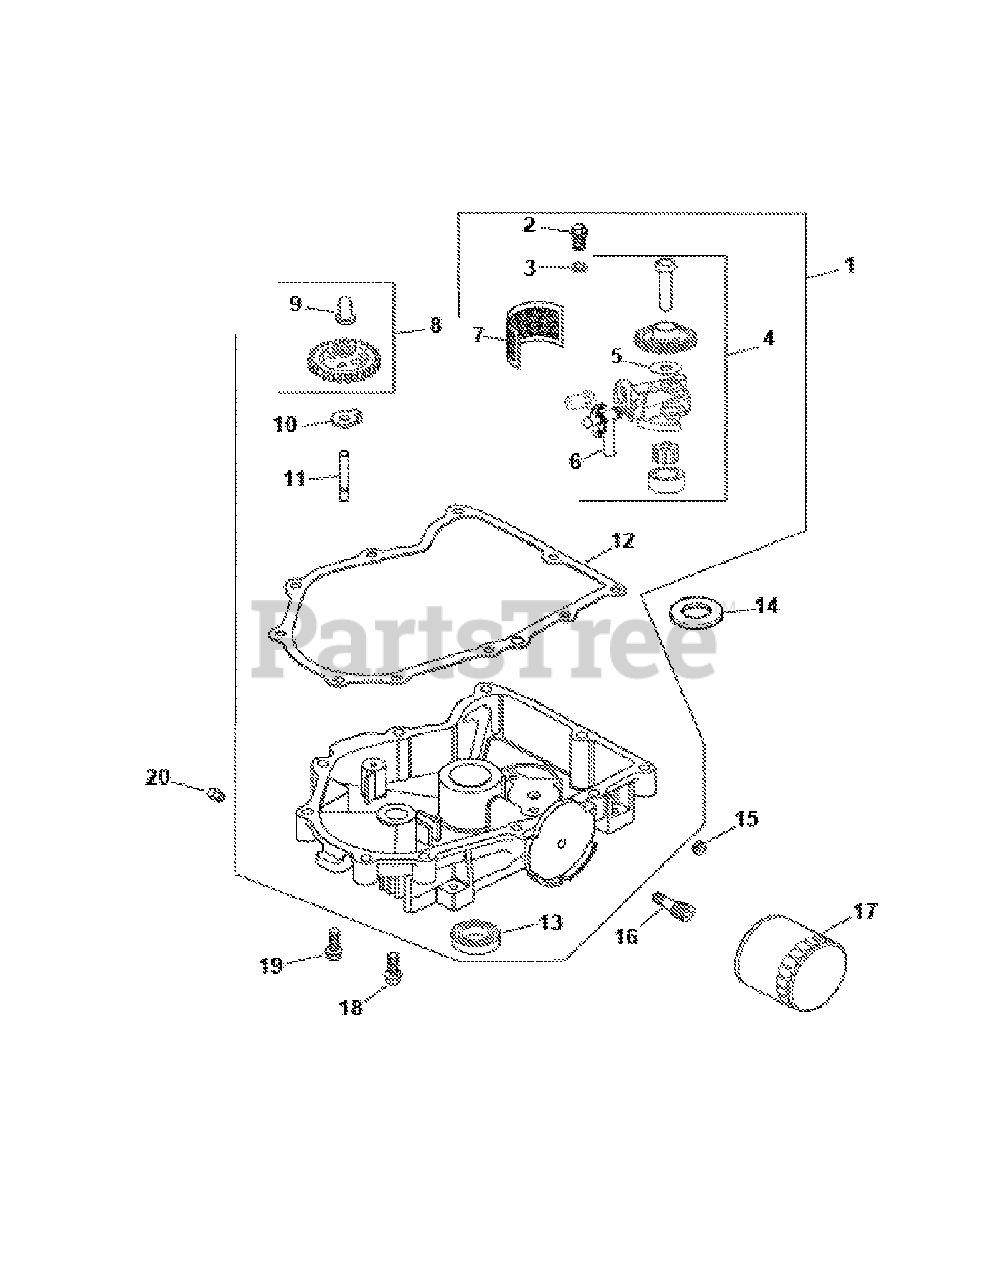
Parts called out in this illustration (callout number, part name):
1	Oil Pan w/Gasket Kit
2	Screw
4	Oil Pump Kit
6	Oil Pickup Tube
8	Governor Gear w/Pin Kit
11	Governor Gear Shaft
12	Oil Pan Gasket
13	Seal
16	Oil Filter Nipple
17	Oil Filter
18	Hex Flange Screw
19	Hex Flange Screw (M6 x 1.0 x 25)
